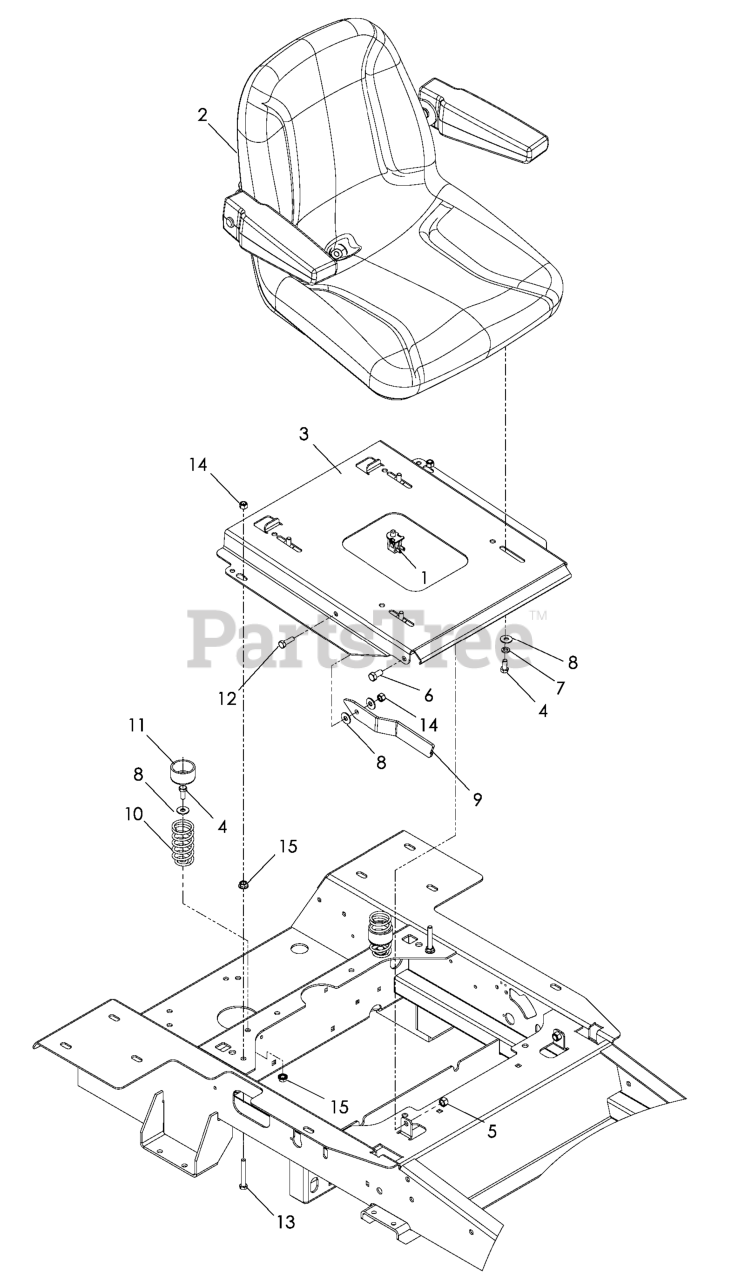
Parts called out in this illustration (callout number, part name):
1	SEAT SWITCH
2	SEAT W/ARMRESTS
3	PAN, SEAT, BLK
4	HCS 5/16C X 3/4
5	NUT 3/8-16 NYLOC
6	SCREW 3/8C X 3/4 HEX CAP
7	WASHER.LOCK.HVY.HLCL.SPR.5/16
8	WASHER 5/16 FLAT
9	ARM, PROP, SEAT
10	SEAT SPRING
11	SPRING CAP
12	HCS 5/16C X 1
13	TAP BOLT 5/16C X 2 1/4
14	NUT 5/16 NYLOC
15	NUT 5/16C WHIZ
